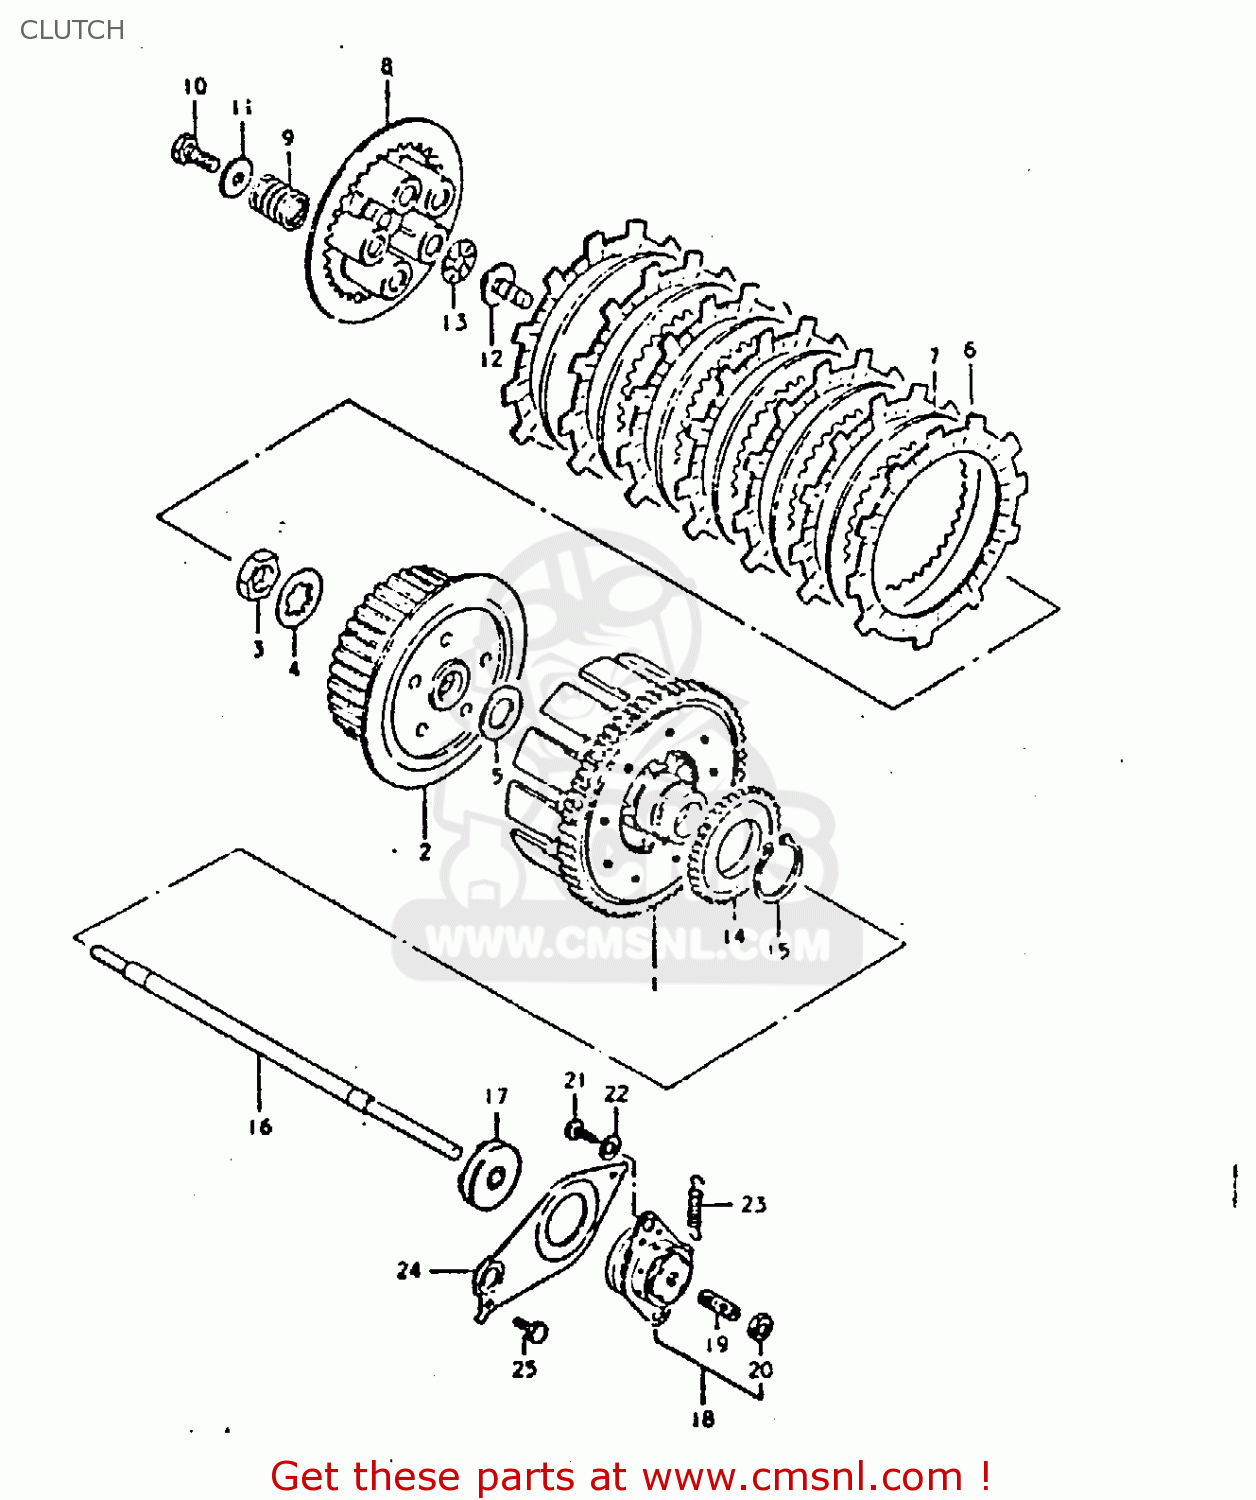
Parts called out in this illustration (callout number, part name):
1	GEAR ASSEMBLY,PRIMARY DRIVE
2	HUB,CLUTCH SLEEVE
3	NUT
4	WASHER
5	WASHER
6	PLATE,CLUTCH DRIVE
7	PLATE,CLUTCH DRIVEN (NAS)
8	DISC,CLUTCH PRESSURE
9	SPRING
10	BOLT(5X16)
11	WASHER (5.5X16X1.2)
12	ROD,CLUTCH RELEASE
13	BEARING(10X22X2.8)
14	GEAR,OIL PUMP DRIVE
15	CIRCLIP
16	ROD,CLUTCH PUSH
17	SEAL,OIL(6X31X10)
18	SCREW ASSEMBLY,CLUTCH RELEASE
19	SCREW
20	NUT 6MM
21	SCREW
22	WASHER
23	SPRING
24	PLATE,CLUTCH PUSH ROD
25	BOLT
